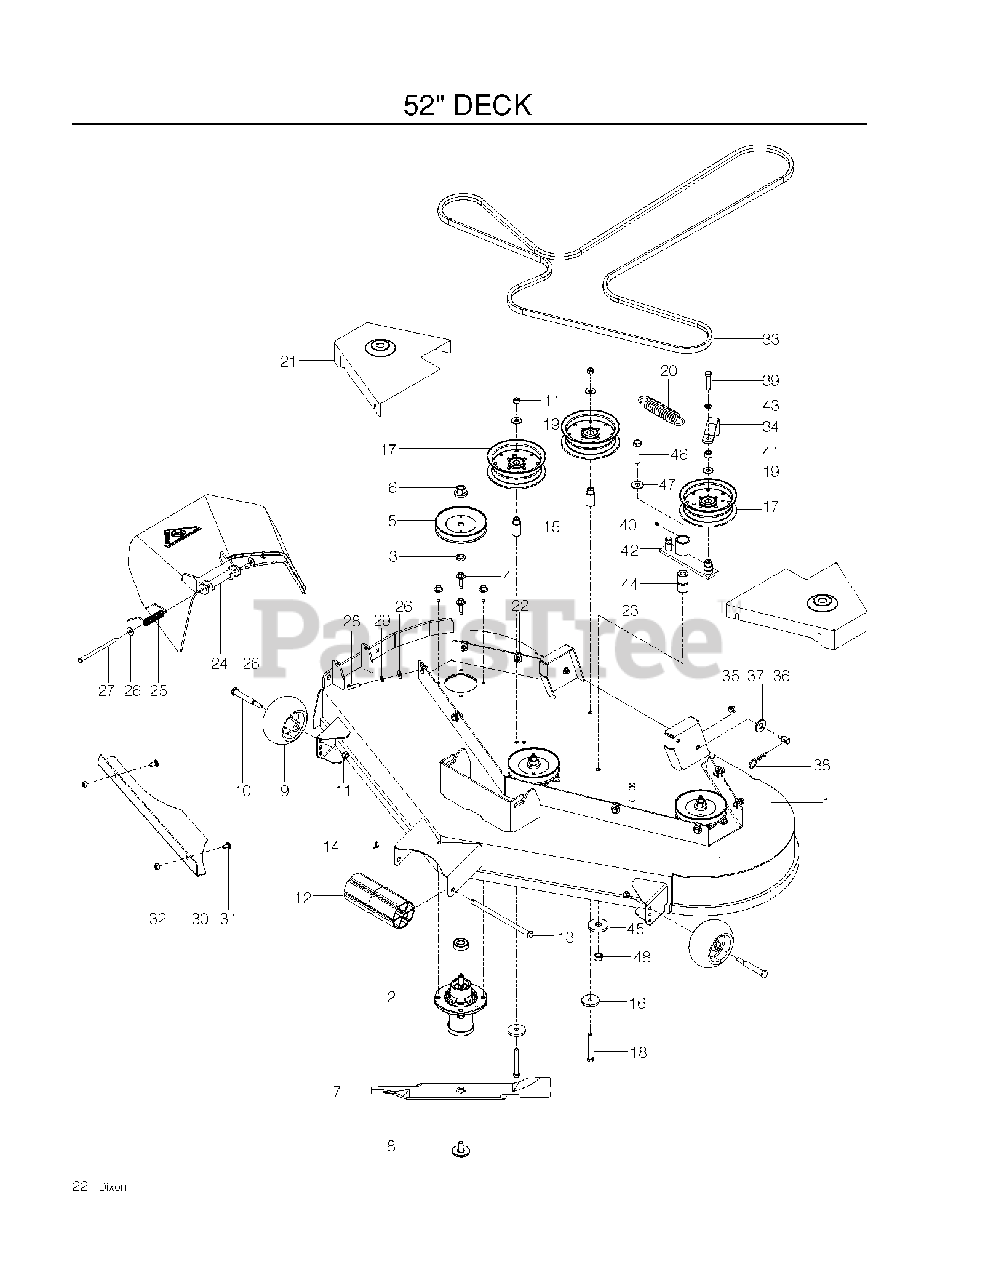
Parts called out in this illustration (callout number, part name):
1	DECK.W/DECALS.RAM.52
2	MANDREL.DECK.ASSEMBLY
3	WASHER-SPACER
4	WASHER HEAD SCREW
5	PULLEY
6	LOCKNUT - 9/16
7	BLADE, 18"
8	BLADE BOLT ASSY-7/16" TB REPL
9	GAUGE WHEEL
10	SHOULDER BOLT 1/2X2-5/8 ZD SPE
11	NUT 3/8-16 NYLOC
12	NOSE ROLLER 48"
13	NOSE ROLLER ROD
14	COTTER PIN 1/8 X 3/4
15	IDLER BUSHING
16	REAR DECK W/DECALS
17	PULLEY, IDLER
18	HCS 3/8C X 3
19	WASHER 3/8 FLAT
21	SHIELD, BELT 52 BLUE RH
22	U-CLIP 5/16-18 NUT RETAINER
23	SHIELD, BELT 52 BLUE LH
24	DISCHARGE CHUTE 52"
25	SPRING - TORSION
26	WASHER 5/16 FLAT
27	PIN-CLEVIS 5/16 DIA X 5.19 ZD
28	HCS 5/16C X 1
29	WASHER 5/16 LOCK
30	CONFINEMENT PLATE, 52"
31	CARRIAGE BOLT 5/16C X 5/8"
32	NUT 5/16 NYLOC
33	BELT, DECK
34	GUIDE, BELT
35	5/16-18 NYLOC FLANGE NUT
36	STUD.FASTNER.W/ANTI-ROTATE
37	WASHER 5/8 FLAT
38	HAIRPIN #4
39	HCS 3/8-16 X 1 3/4 GR5
40	ZERK
42	IDLER ARM
43	FLAT WASHER 5/16 SAE
44	PIVOT BUSHING
45	WASHER, SUPPORT
46	HCS 1/2C X 3 1/4
47	WASHER 1/2 FLAT
48	NUT 1/2-13 HEX NYLOC ZD
